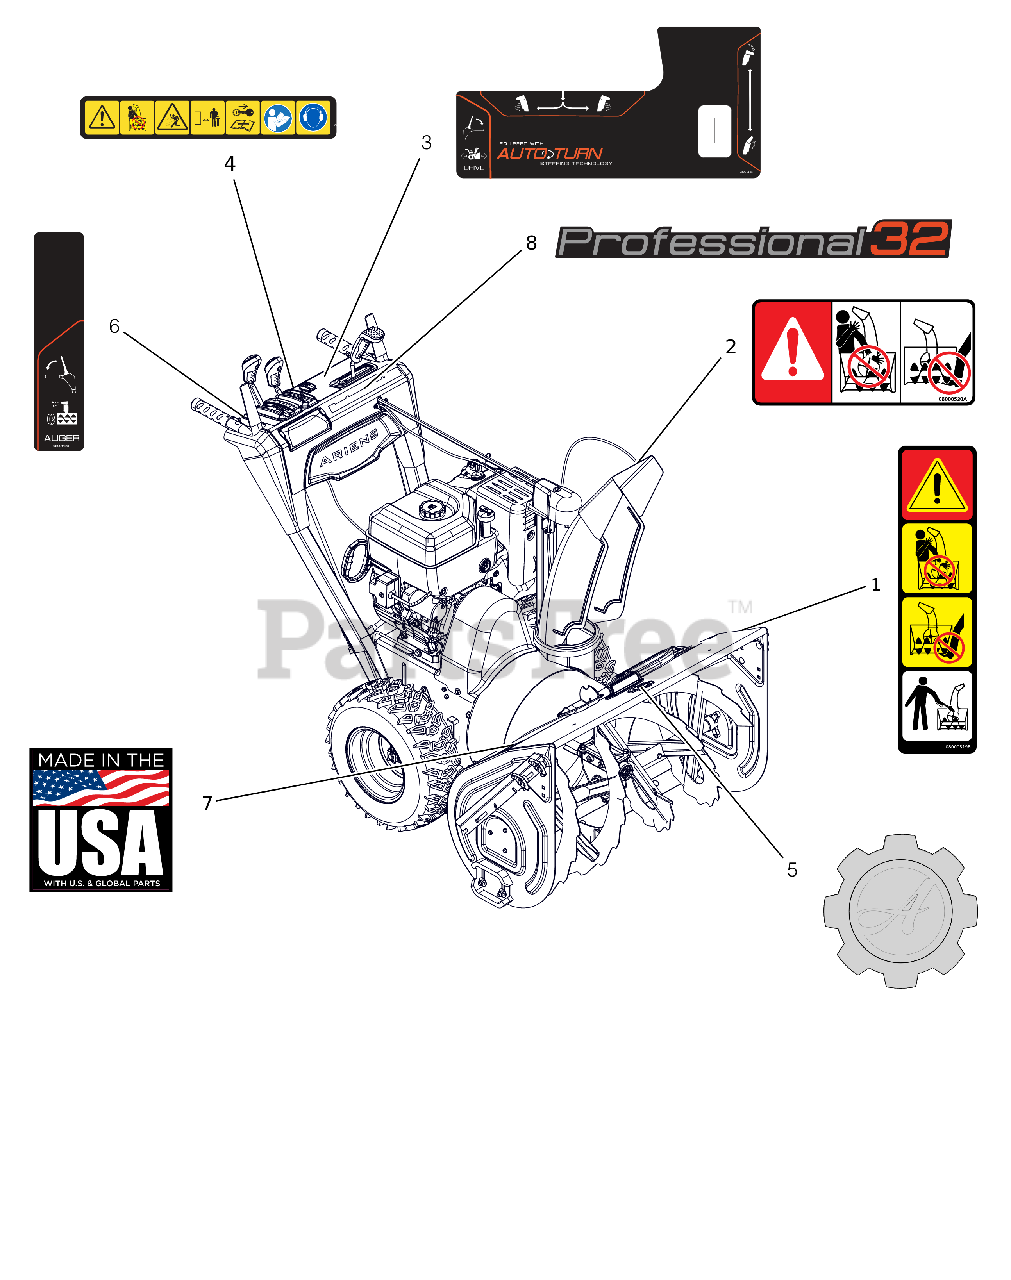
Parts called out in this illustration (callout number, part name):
1	DECAL, DANGER - ROTATING PARTS
2	DECAL, DANGER
3	DECAL,CONTROL-LG QT2
4	DECAL,DASH - SAFETY
5	DECAL, ARIENS-GEAR BADGE -THK
6	DECAL,CONTROL-RH CONTROL
7	DECAL, MADE IN USA
8	DECAL, DASH - PRO 32
